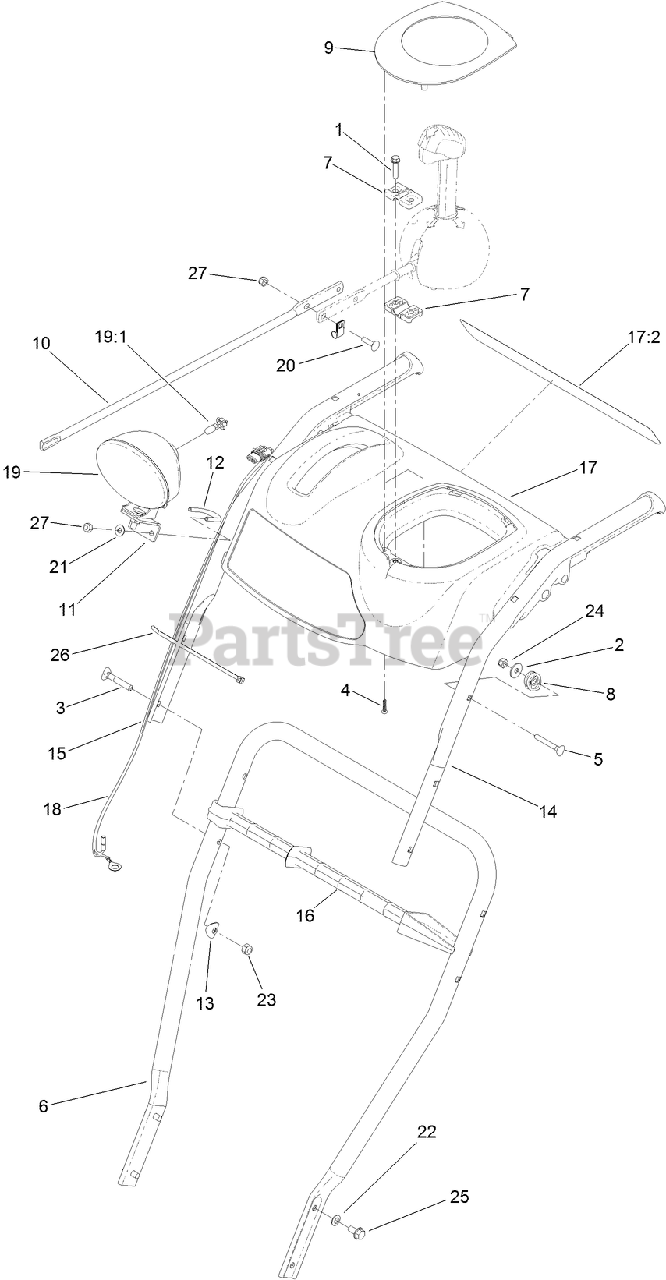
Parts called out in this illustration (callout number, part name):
1	SCREW-PLASTITE, HWH
2	WASHER-PLAIN
3	SCREW-HANDLE
4	SCREW-PPH
5	BOLT-CARR
6	HANDLE-LOWER
7	SUPPORT-ROD
8	CLAMP-CABLE
9	COVER-PANEL, CONTROL
10	ROD-CHUTE, FRONT
11	BRACKET-LIGHT
12	CLAMP-LIGHT
13	WASHER-CUP
14	HANDLE-UPPER, LH
15	HANDLE-UPPER, RH
16	STICK-CLEANOUT
17	PANEL-CONTROL
17:2	DECAL-WARNING
18	HARNESS-WIRE, HEADLIGHT
19	HEADLAMP ASM
19:1	LAMP-12 VOLT
20	BOLT-CARR
21	WASHER-PLAIN
22	WASHER-BELLEVILLE
23	NUT-HEX
24	NUT-HEX
25	SCREW-HWHTF
26	TIE-CABLE
27	NUT-HEX
